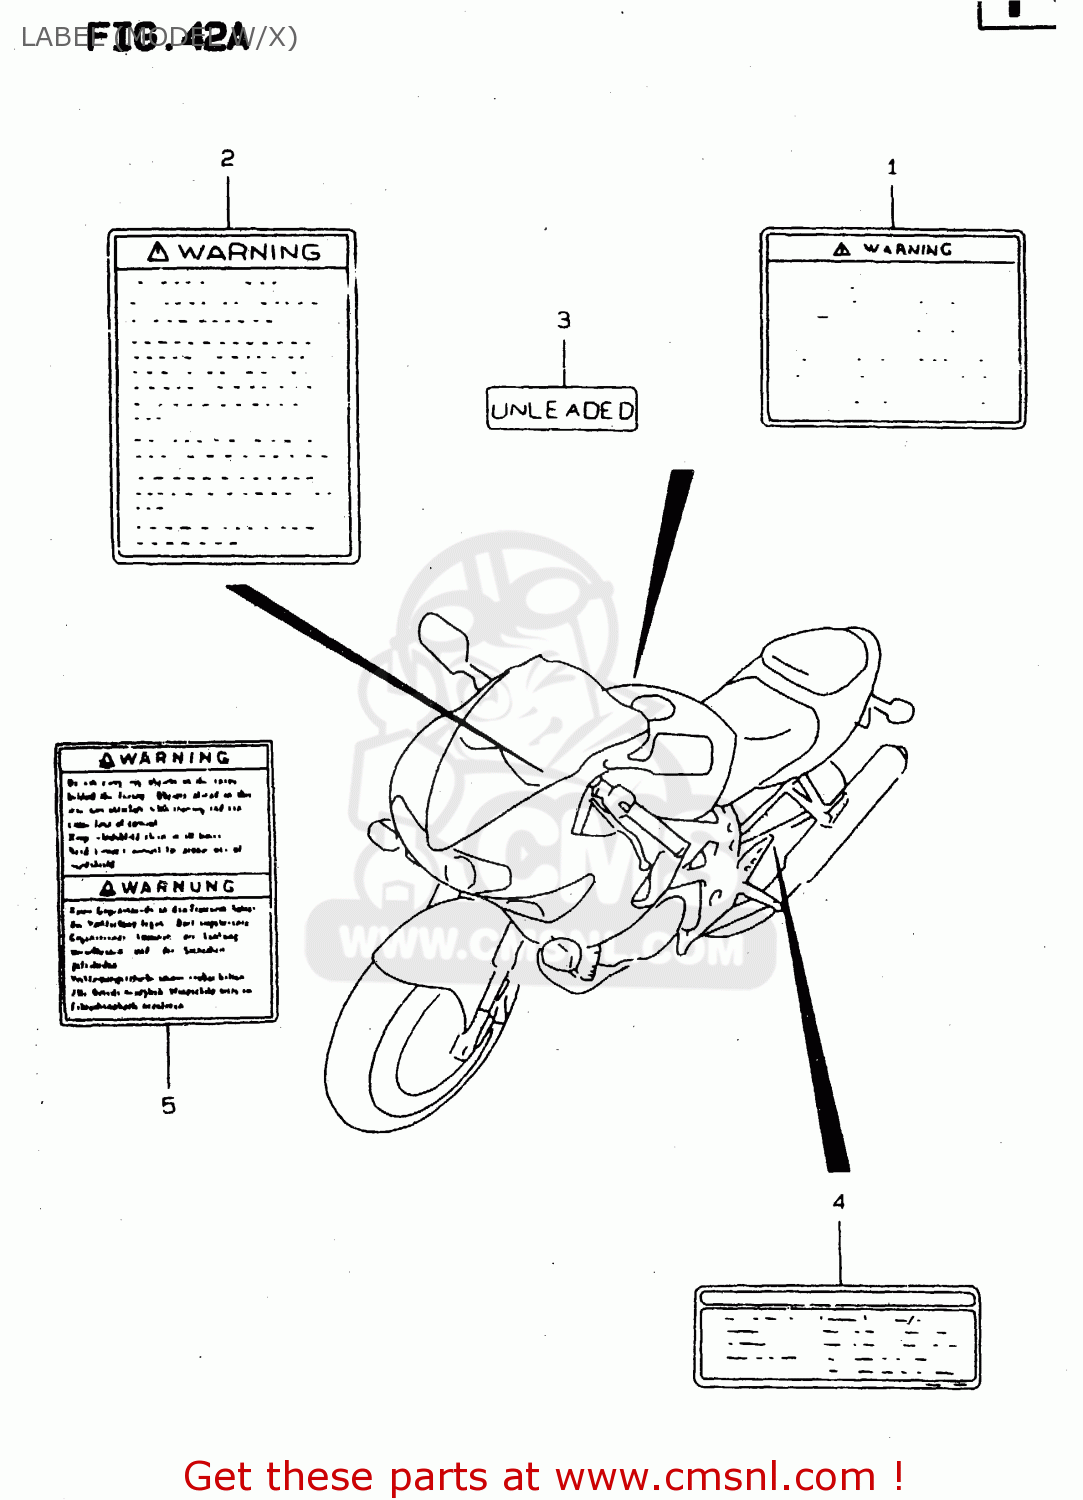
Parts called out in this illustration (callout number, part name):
1	LABEL,WARNING
2	LABEL (WARNING SCREEN)
3	LABEL,CAUTION
4	LABEL,TIRE INFORMATION
5	LABEL,WARNING STEERING
6	O.M. TL1000S W
